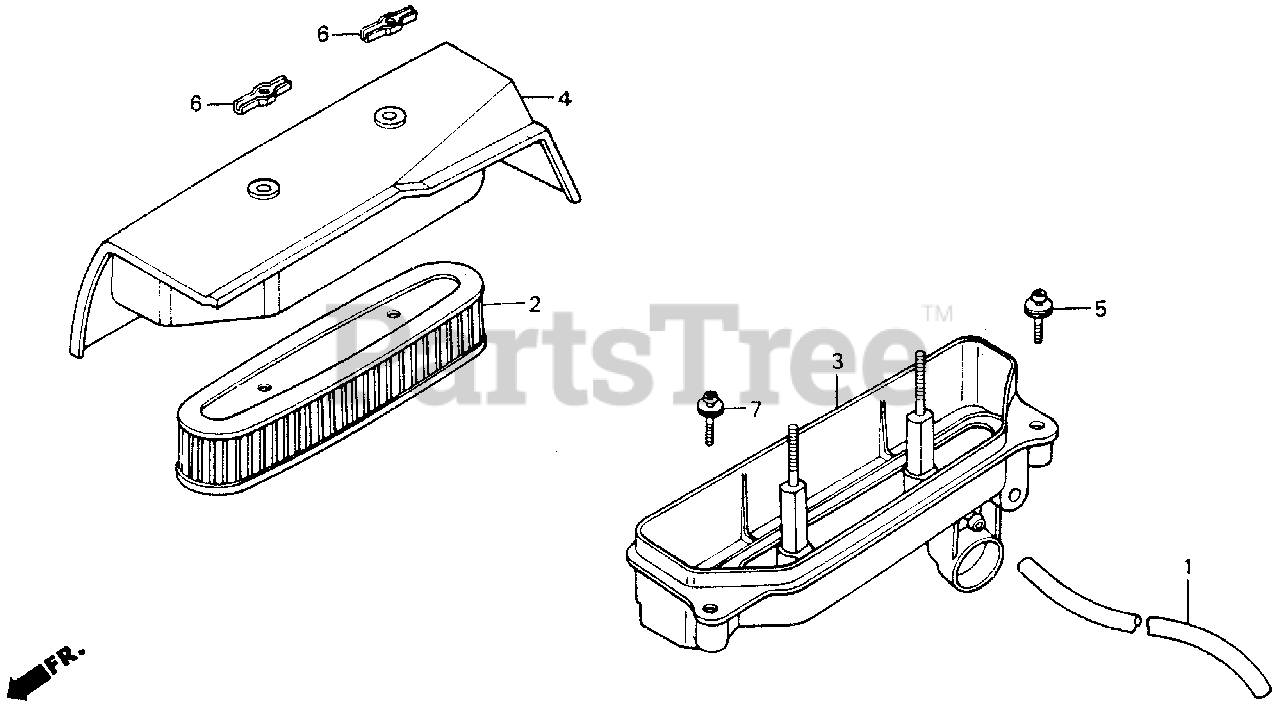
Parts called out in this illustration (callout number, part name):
1	TUBE ASSY., BREATHER (NOT AVAILABLE)
1	TUBE, BREATHER (NOT AVAILABLE)
2	ELEMENT, AIR CLEANER
3	HOUSING, AIR CLEANER (NOT AVAILABLE)
4	COVER, AIR CLEANER (NOT AVAILABLE)
5	SCREW-WASHER (6X32)
6	WINGNUT (6MM) (BLACK)
7	SCREW-WASHER (6X35)
